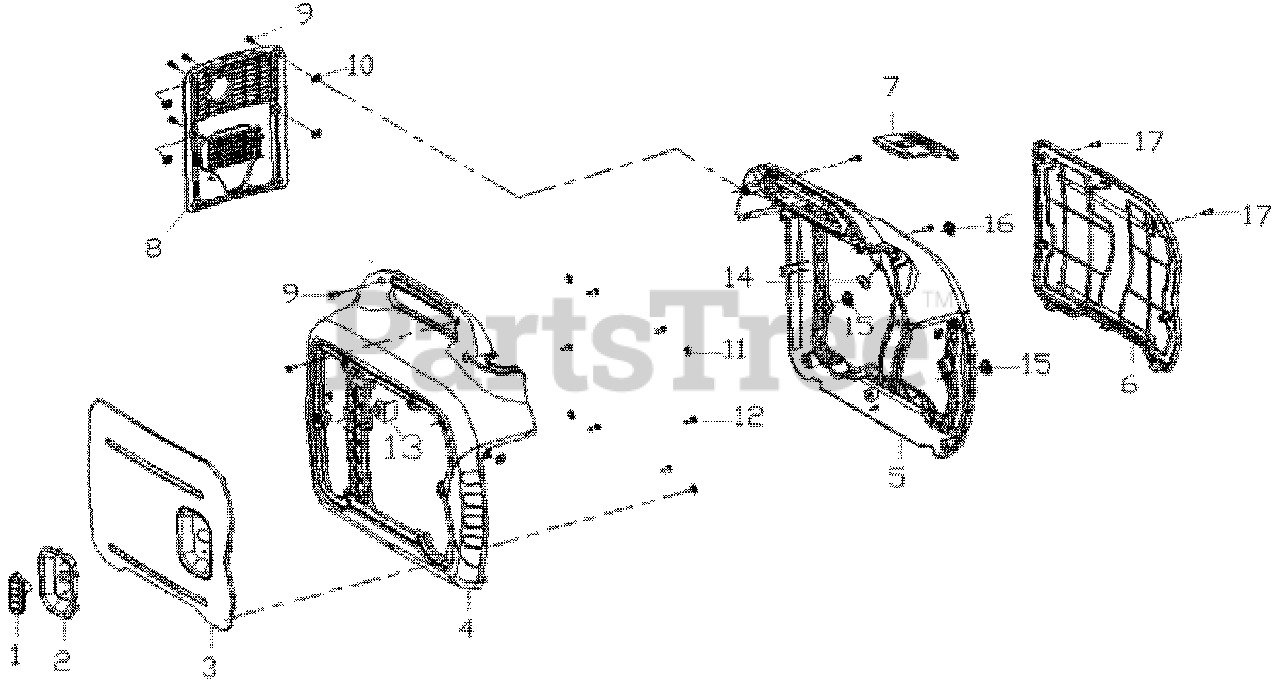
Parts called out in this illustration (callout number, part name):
2	LEASH HANDLE ADORNMENT HOOD
3	LEFT APPEARANCE COVER-GRAVELY
4	LEFT COLUMN
5	OUTER COLUMN
6	RIGHT APPEARANCE COVER-GRAVELY
7	SPARK PLUG MAINTENANCE COVER
9	SCREW FLAT MAT COMBINATION
10	CLIP NUT
11	LOCK WASHER
12	SCREW, PAN, M4×15
13	BUFFER RUBBER
14	BUFFER RUBBER
15	RUBBER TANK CUSHION
16	RUBBER TANK CUSHION
